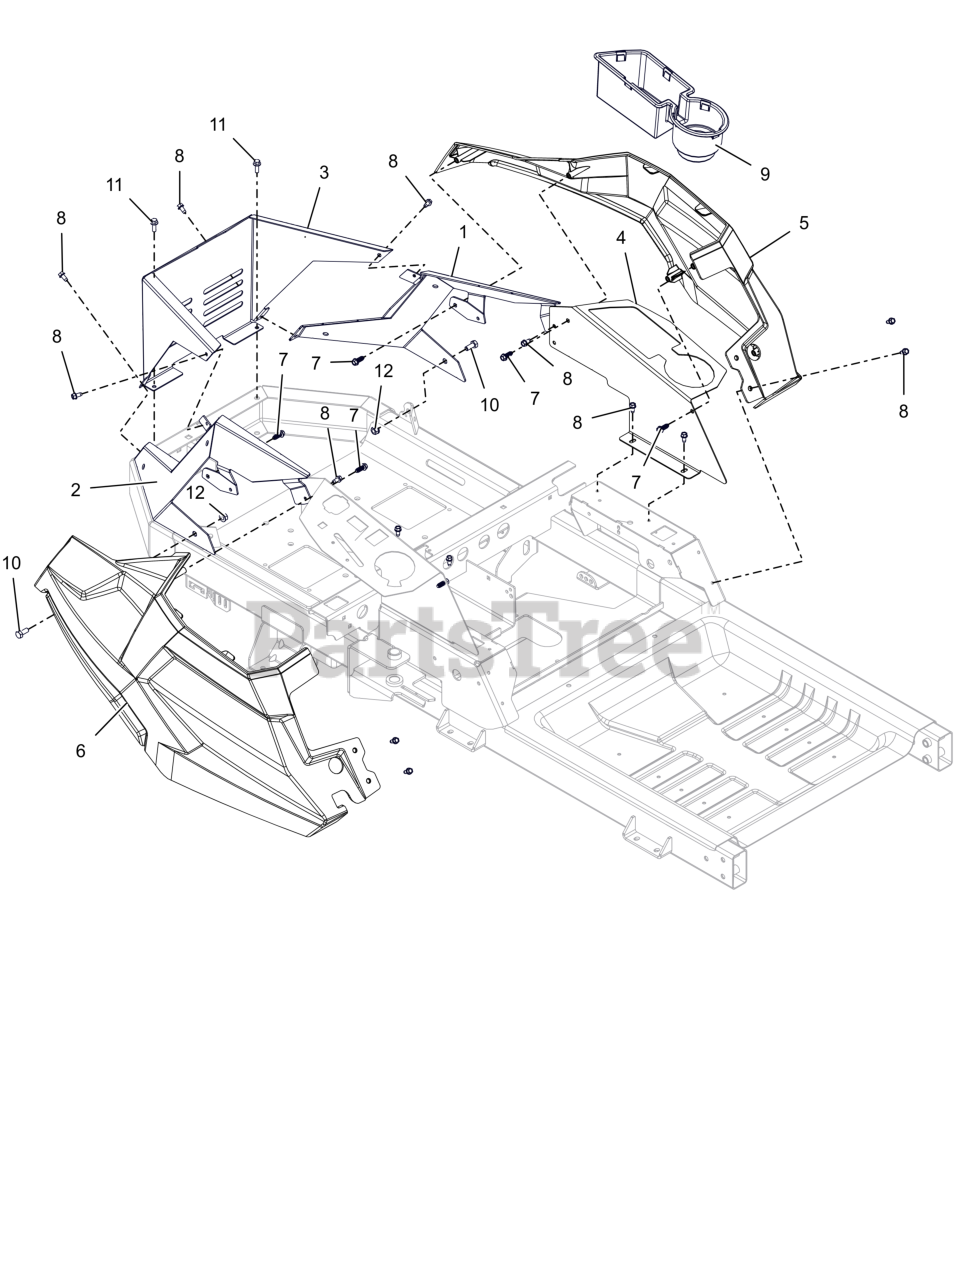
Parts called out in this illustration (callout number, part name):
1	WRAP, REAR - LH (RED)
2	WRAP, REAR - RH (RED)
3	WRAP, REAR (BLACK)
4	PANEL, CUP HOLDER (RED)
5	FENDER, LH
6	FENDER, RH
7	SCR-.312X.75 #14H H/W/H H/L CZ
8	SCR-TAP .25-20X.50 HWH ZCC
9	INSERT, CUP/STORAGE HOLDER
10	BLT,HEX .31-18X.75 G5 ZCC
11	BLT,HEX-FLG .25-20X.75 G5 BFP
12	NUT-LK-TOP-FLG .312-18 GF ZCC
